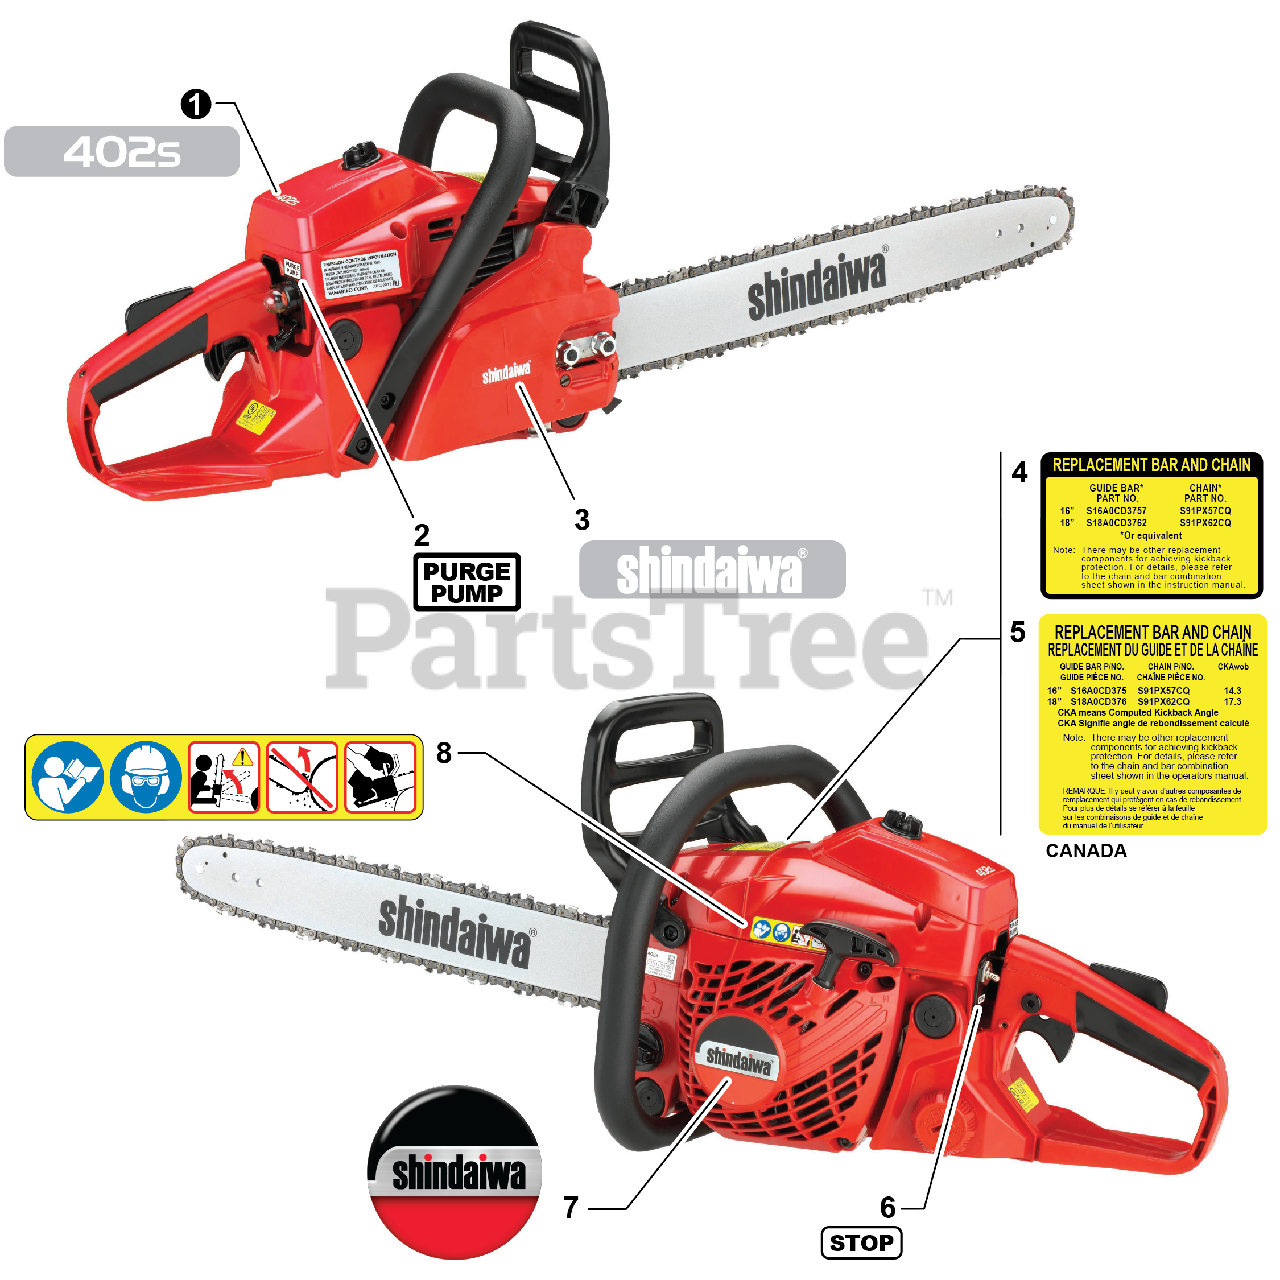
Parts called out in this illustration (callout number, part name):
1	LABEL - MODEL 402s
2	LABEL, PURGE PUMP
3	LABEL - shindaiwa
4	LABEL, BAR & CHAIN
5	LABEL, BAR & CHAIN
6	LABEL, STOP
7	LABEL, STARTER - shindaiwa
8	LABEL, CAUTION
